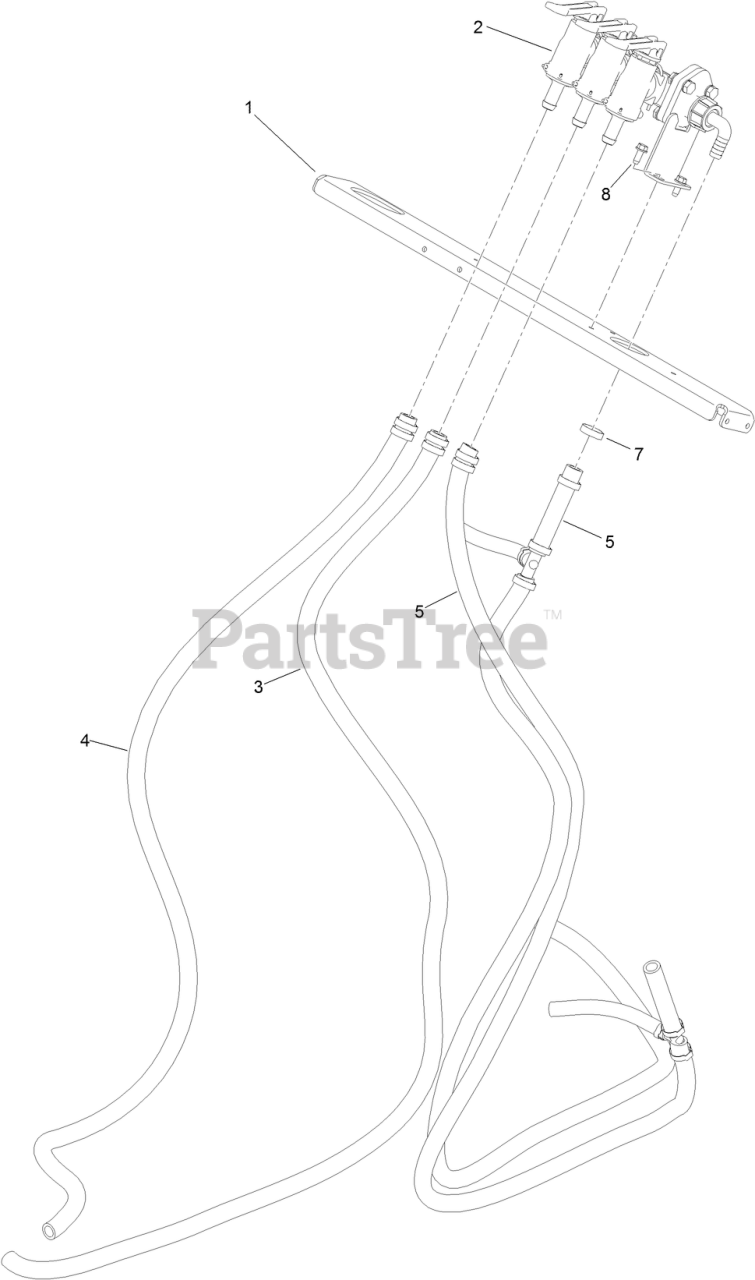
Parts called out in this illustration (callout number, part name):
1	CROSSMEMBER-COLUMN
2	MANIFOLD-VALVE, CONTROL
3	HOSE-WATER
4	HOSE-WATER
5	HOSE ASM
8	SCREW-HWH
